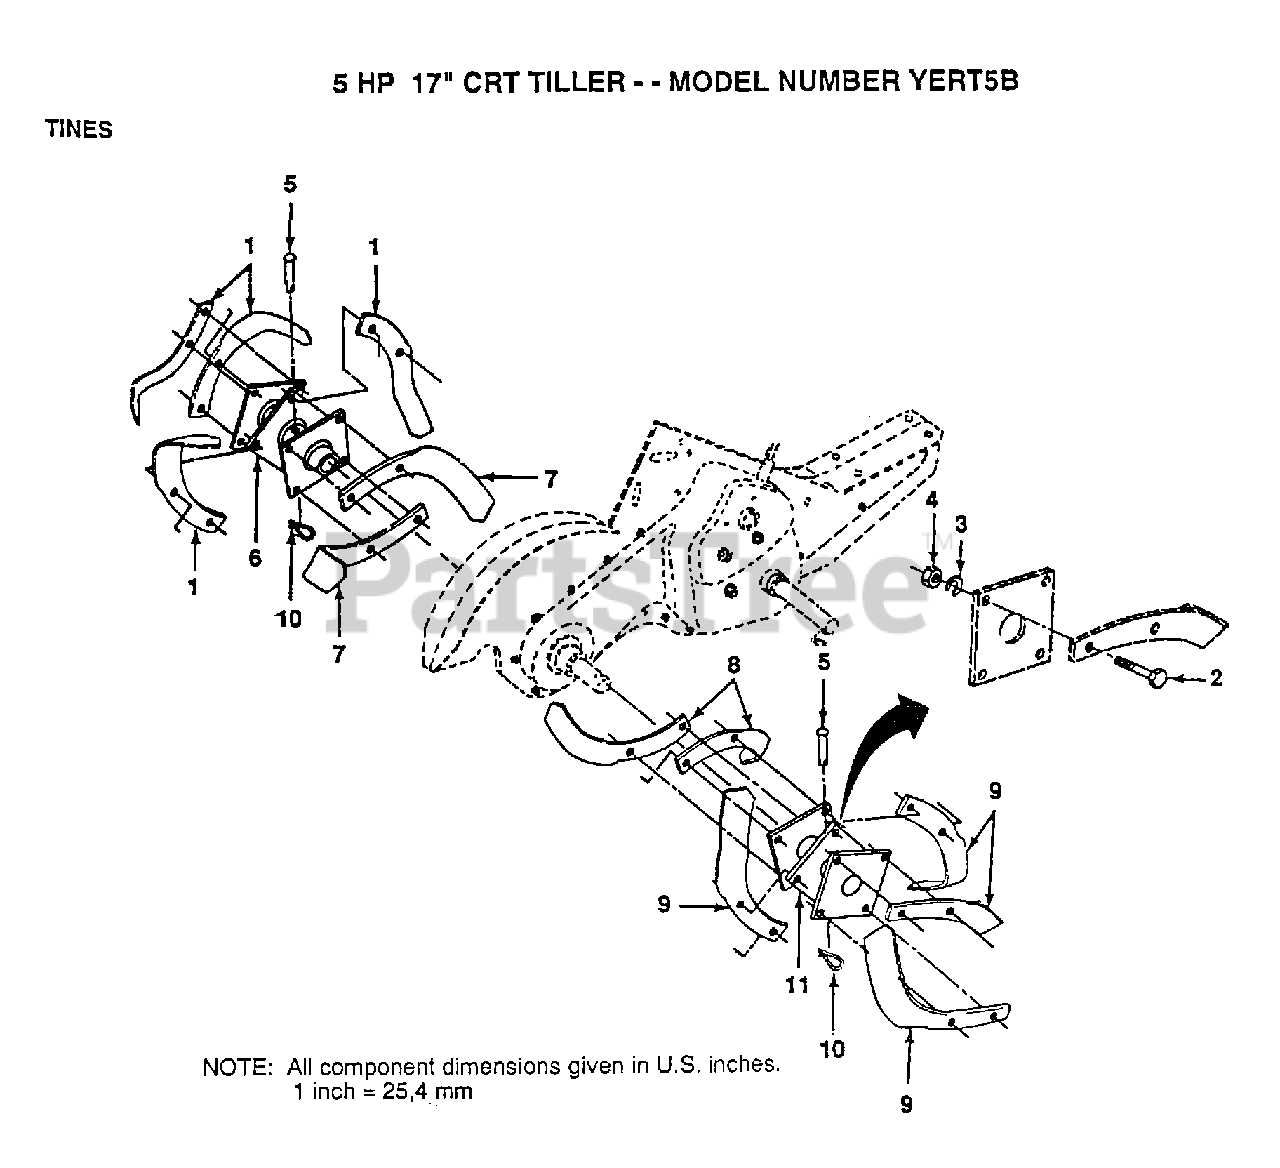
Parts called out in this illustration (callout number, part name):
2	BOLT
3	LOCKWASHER
5	RIVET.PAN HD.1.75
6	TINE ASSY LH CRT
7	"TINE.LH.12"""
8	"TINE.RH.12"""
10	RETAINER.SPRING
11	TINE ASSY RH CRT
